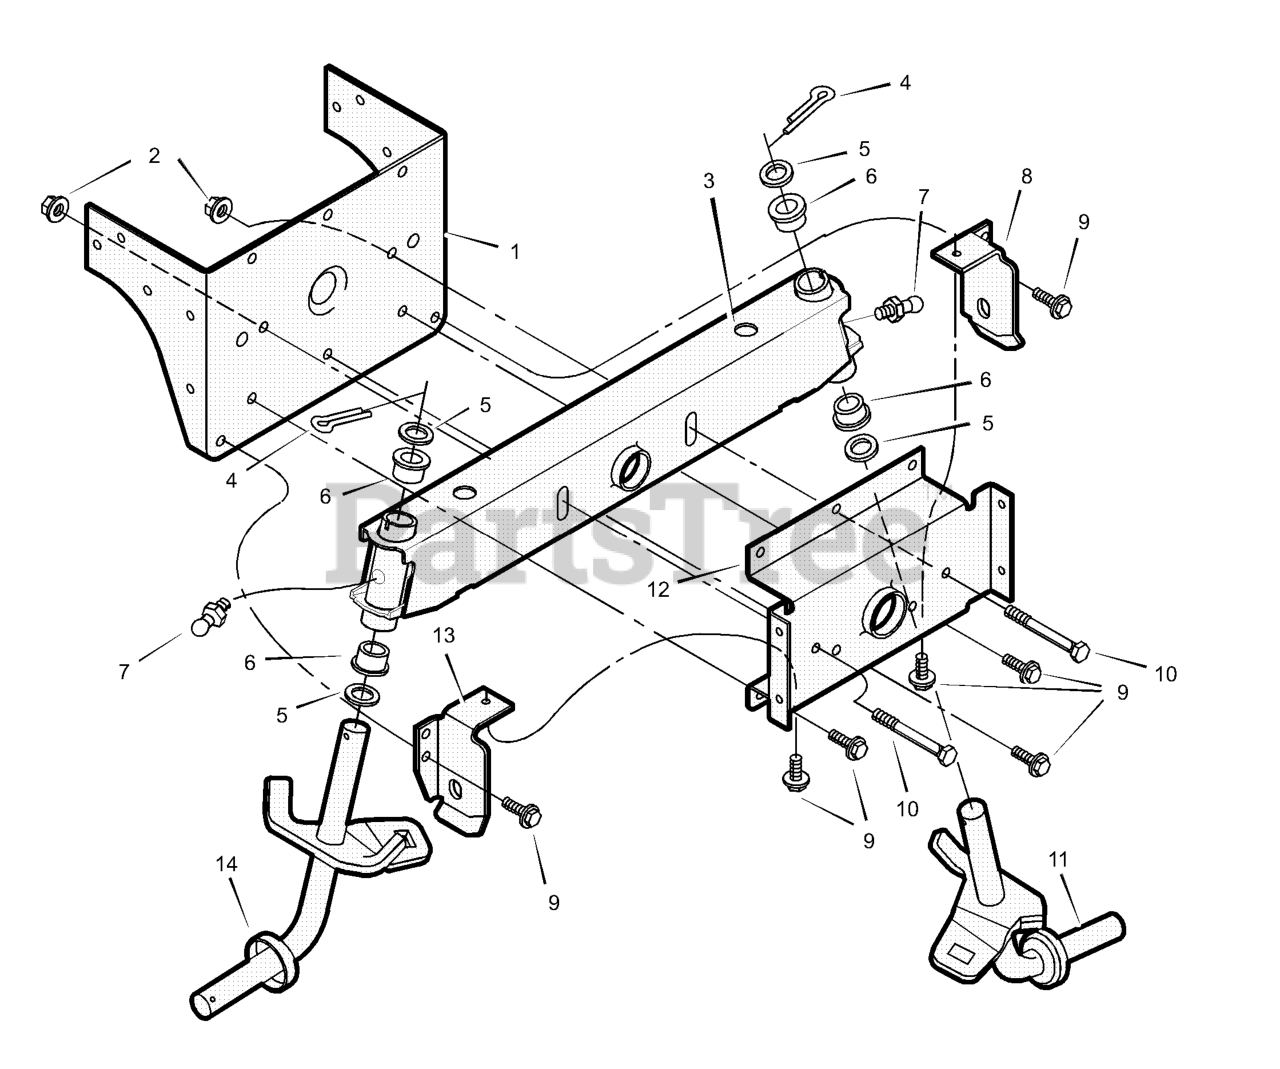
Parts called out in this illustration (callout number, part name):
1	Bracket, Rear Hanger
2	Nut, Flange
3	Axle Assembly
4	Pin, Hair
6	Bearing, Spindle
7	Fitting, Lub
8	Hanger, Left Deck
11	Spindle Assembly, Left
12	Hanger, Axle
13	Hanger, Right Deck
14	Spindle Assembly, Right
